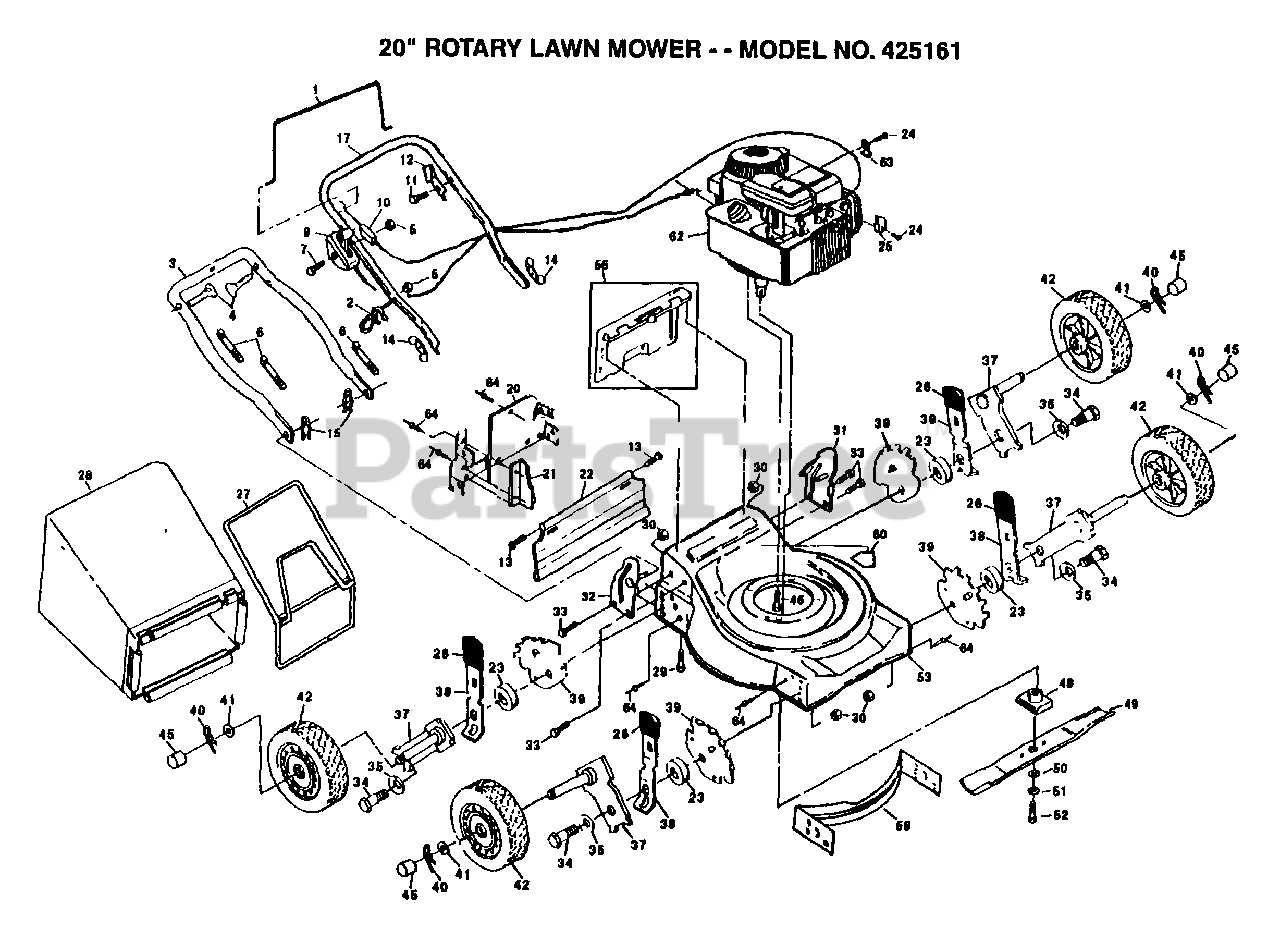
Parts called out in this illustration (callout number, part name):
1	CONTROL BAR PM
2	ROPE GUIDE
4	BOLT.HANDLE.LM
7	SCREW.HXHD.WASH.
9	CONTROL THROTTLE
10	"CABLE,ENG ZONE CO"
11	TAPPING SCREW
12	"BRKT,UPSTOP"
13	HINGE SCREW
14	"NUT,WING PM"
15	HAIRPIN COTTER
20	PLATE.BACK.20RD
22	SKIRT.PUSH.20RD
24	SCREW PM
25	CABLE CLAMP
26	KNOB PM
27	CATCHER FRAME
28	GBAG.250B1.BLK
29	SCREW
30	LOCKNUT PM
33	SCREW
34	BOLT SHLD 3/8-16
35	"WASHER, BELLEVIL."
37	AXLE ARM
38	SPRING SELECTOR
39	BRACKET.ADJ.9POS.
40	RETAINER CLIP PM
41	WASHER
42	WHL. & TIRE ASM.
45	HUB CAP-PLASTIC
46	SCREW
48	BLADE ADAPTOR
49	BLADE.STAND.20INC
50	"WASHER,HARDEN"
51	LOCKWASHER
52	SCREW
53	KIT.HSG.20RD
56	"KIT, REAR DOOR PM"
60	DECAL-DANGER PM
63	GUIDE CLIP PM
64	BLIND RIVET
